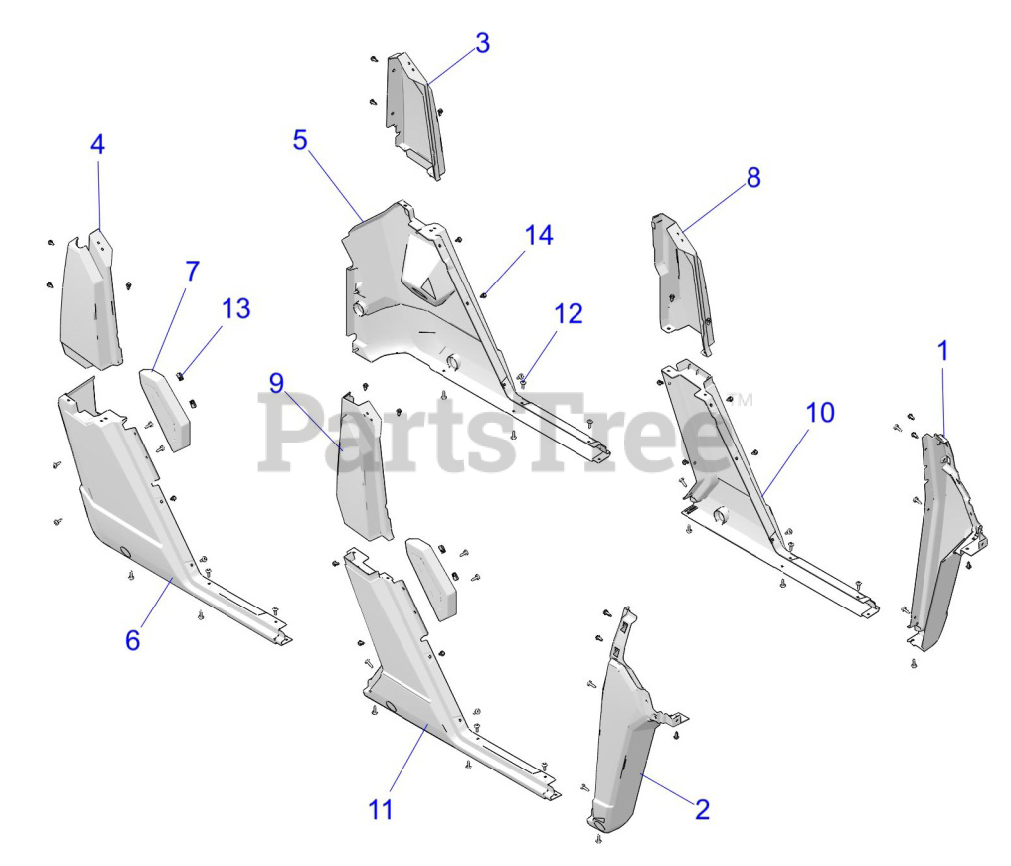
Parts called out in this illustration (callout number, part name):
1	COVER-FRONT-LH-BLK
2	COVER-FRONT-RH-BLK
3	FENDER-REAR-UPPER-LH-BLK
4	FENDER-REAR-UPPER-RH-BLK
5	COVER-ROCKER-LH-BLK
6	COVER-ROCKER-RH-BLK
7	COVER-SEAT PIVOT-BLK
8	COVER-ROPS PILLAR- LH- BLK
9	COVER-ROPS PILLAR-PH-BLK
10	COVER-ROCKER-CREW-LH-BLK
11	COVER-ROCKER-CREW-RH-BLK
12	SCR-TXTH-M6X1.0X25 RIE
13	NUT-M6-1.0- U-TYPE (2.5-3.8)
14	RIVET-TUFLOK-.315-.325X.787 (5
